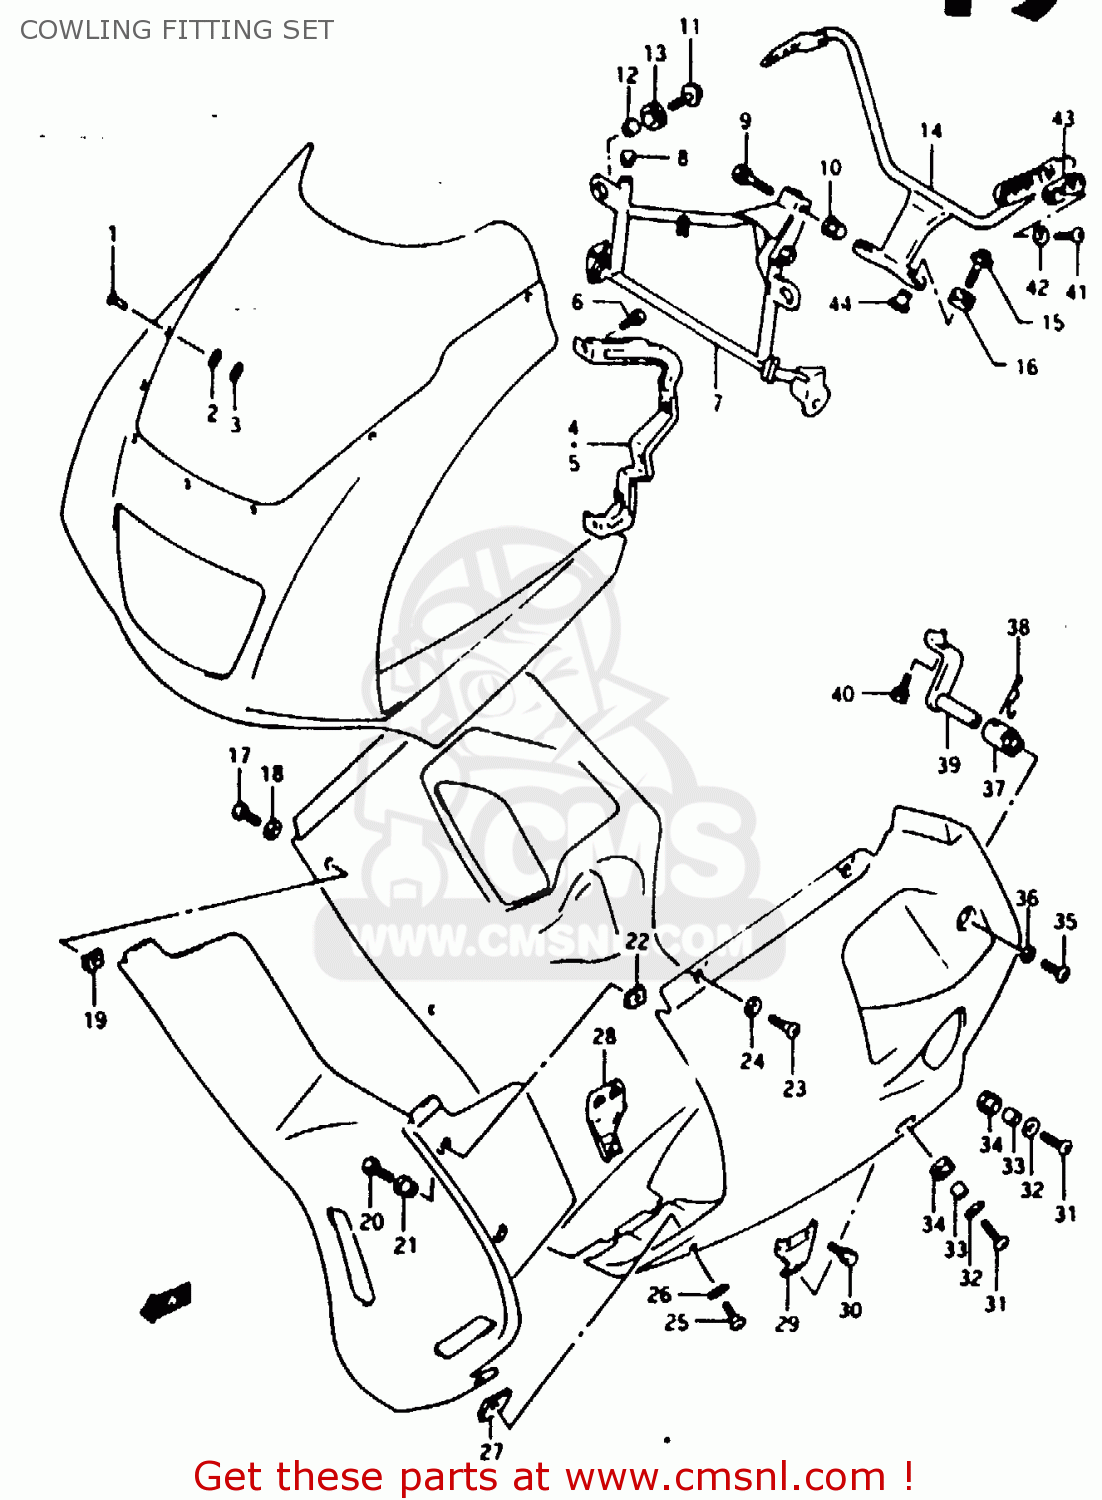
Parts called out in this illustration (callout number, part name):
1	PIN,WINDSCREEN
2	CUSHION
3	NUT
4	BRACKET,HEADLAMP FIT,R
5	BRACKET,HEADLAMP FIT,L
6	SCREW
7	BRACE,COWLING
8	CAP(OD:14)
9	BOLT
10	NUT
11	BOLT 6X20
12	SPACER (6.1X9X10)
13	CUSHION
14	BRACE,RR VIEW MIRRORR
15	BOLT
16	CUSHION
17	SCREW(5X16)
18	WASHER(7X13X0.6)
19	NUT,RH & CTR UNDER COWLING
20	SCREW
21	WASHER(5.2X14X1.5)
22	NUT
23	SCREW(5X16)
24	WASHER(7X13X0.6)
25	SCREW(5X16)
26	WASHER(7X13X0.6)
27	NUT,RH & CTR UNDER COWLING
28	BRACKET, LOWER RH
29	BRACKET, LOWER LH
30	BOLT
31	SCREW(6X18)
32	WASHER(6.5X18X1)
33	SPACER (6.1X9X10)
34	CUSHION
35	SCREW(6X18)
36	WASHER
37	PLUG,UNDER COWL FTG,CTR
38	PIN,UNDER COWLING FITTING PIPE
39	BRACKET,COWLING FITTING CTR
40	BOLT
41	SCREW(6X12)
42	WASHER(6.2X19X1.5)
43	CUSHION,RR VIEW MIRRORR
44	WASHER
